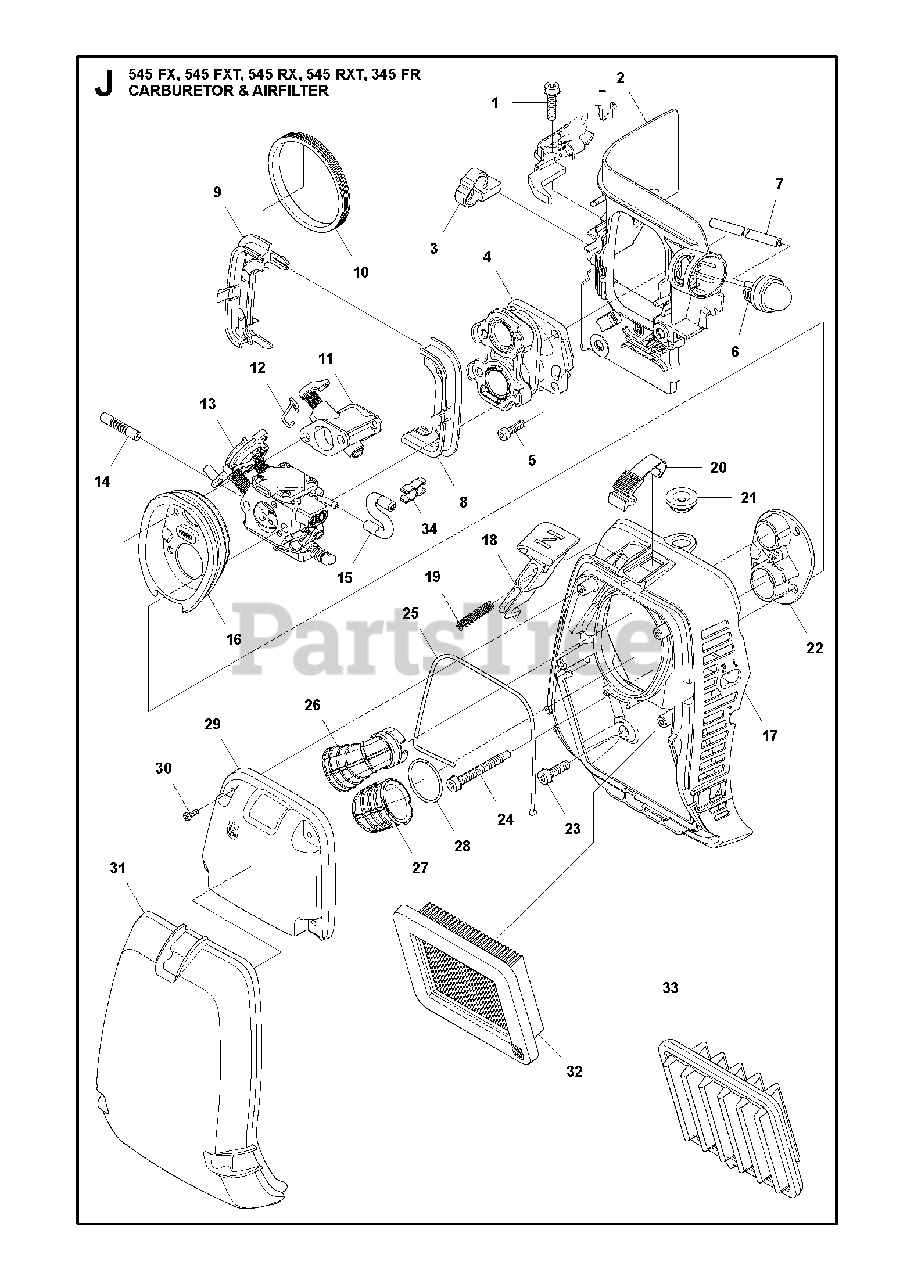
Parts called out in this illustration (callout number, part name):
2	INSULATION WALL
4	INLET PIPE
6	AIR PURGE BUBBLE
10	SEALING RING
13	CARBURETOR
14	SUCTION HOSE
17	FILTER HOLDER ASSY
18	CHOKE CONTROL
22	COVER PLATE
23	SCREW IHSCFM
26	INLET PIPE AIR HEAD
27	INLET PIPE ASSY
28	LOCKING SPRING
29	COVER LID ASSY
31	FILTER COVER
32	FILTER AIR FILTER PAPER
